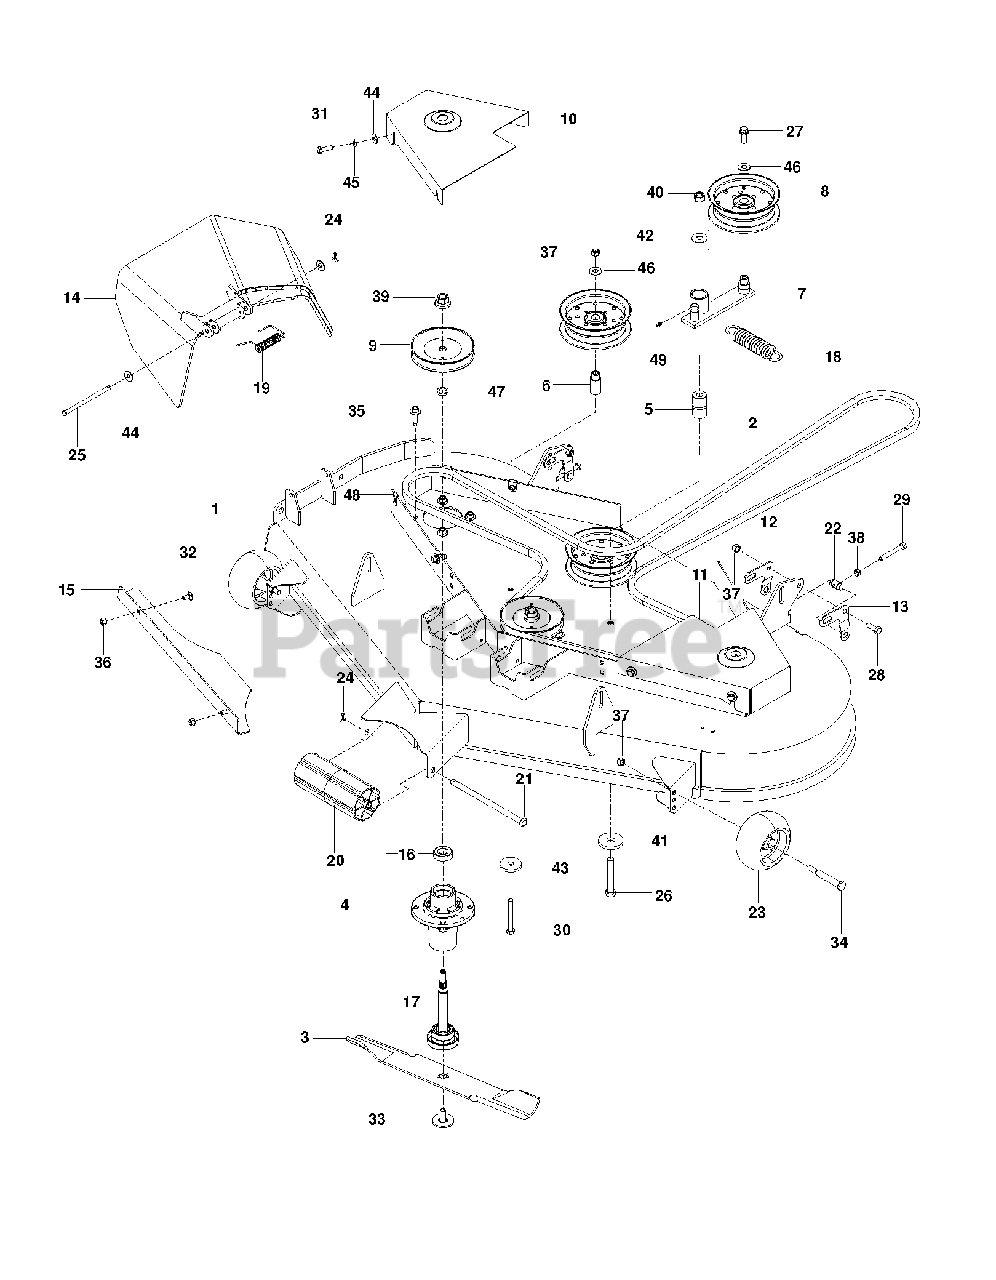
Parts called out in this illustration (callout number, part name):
2	BELT, B, 148.5
3	BLADE, 18"
4	MANDREL ASM, CAST IRON
5	PIVOT BUSHING
6	IDLER BUSHING
7	IDLER ARM
8	PULLEY, IDLER
10	BELT SHIELD, RIGHT 52, ORG
11	BELT SHIELD, LEFT 52, ORG
12	PITCH, ADJUST, RT
13	PITCH, ADJUST, LT
14	DISCHARGE CHUTE 52"
15	CONFINEMENT PLATE, 52"
16	BEARING, BALL
17	SHAFT ASM MANDREL
19	SPRING - TORSION
20	NOSE ROLLER 48"
21	ROD.ROLLER.NOSE.NARROW.48"
22	TRUNION, PITCH
24	COTTER PIN 1/8 X 3/4
25	PIN-CLEVIS 5/16 DIA X 5.19 ZD
26	HCS 1/2C X 3 1/4
27	HCS 3/8C X 1 SERRATED HEAD
28	HCS 3/8C X 1
29	HCS 5/16-18 X 2 1/2 TPBLT
30	HCS 3/8C X 3
31	HCS 5/16C X 3/4
32	CARRIAGE BOLT 5/16C X 5/8"
34	SHOULDER BOLT 1/2X2-5/8 ZD SPE
36	NUT 5/16 NYLOC
37	NUT 3/8-16 NYLOC
38	NUT 5/16C HEX
40	NUT 1/2-13 HEX NYLOC ZD
41	WASHER, SUPPORT
42	WASHER 1/2 FLAT
43	SPINDLE WASHER
44	WASHER 5/16 FLAT
45	WASH 5/16 DISC SPRING ZD
46	WASHER 3/8 FLAT
48	U-CLIP 5/16-18 NUT RETAINER
49	ZERK
